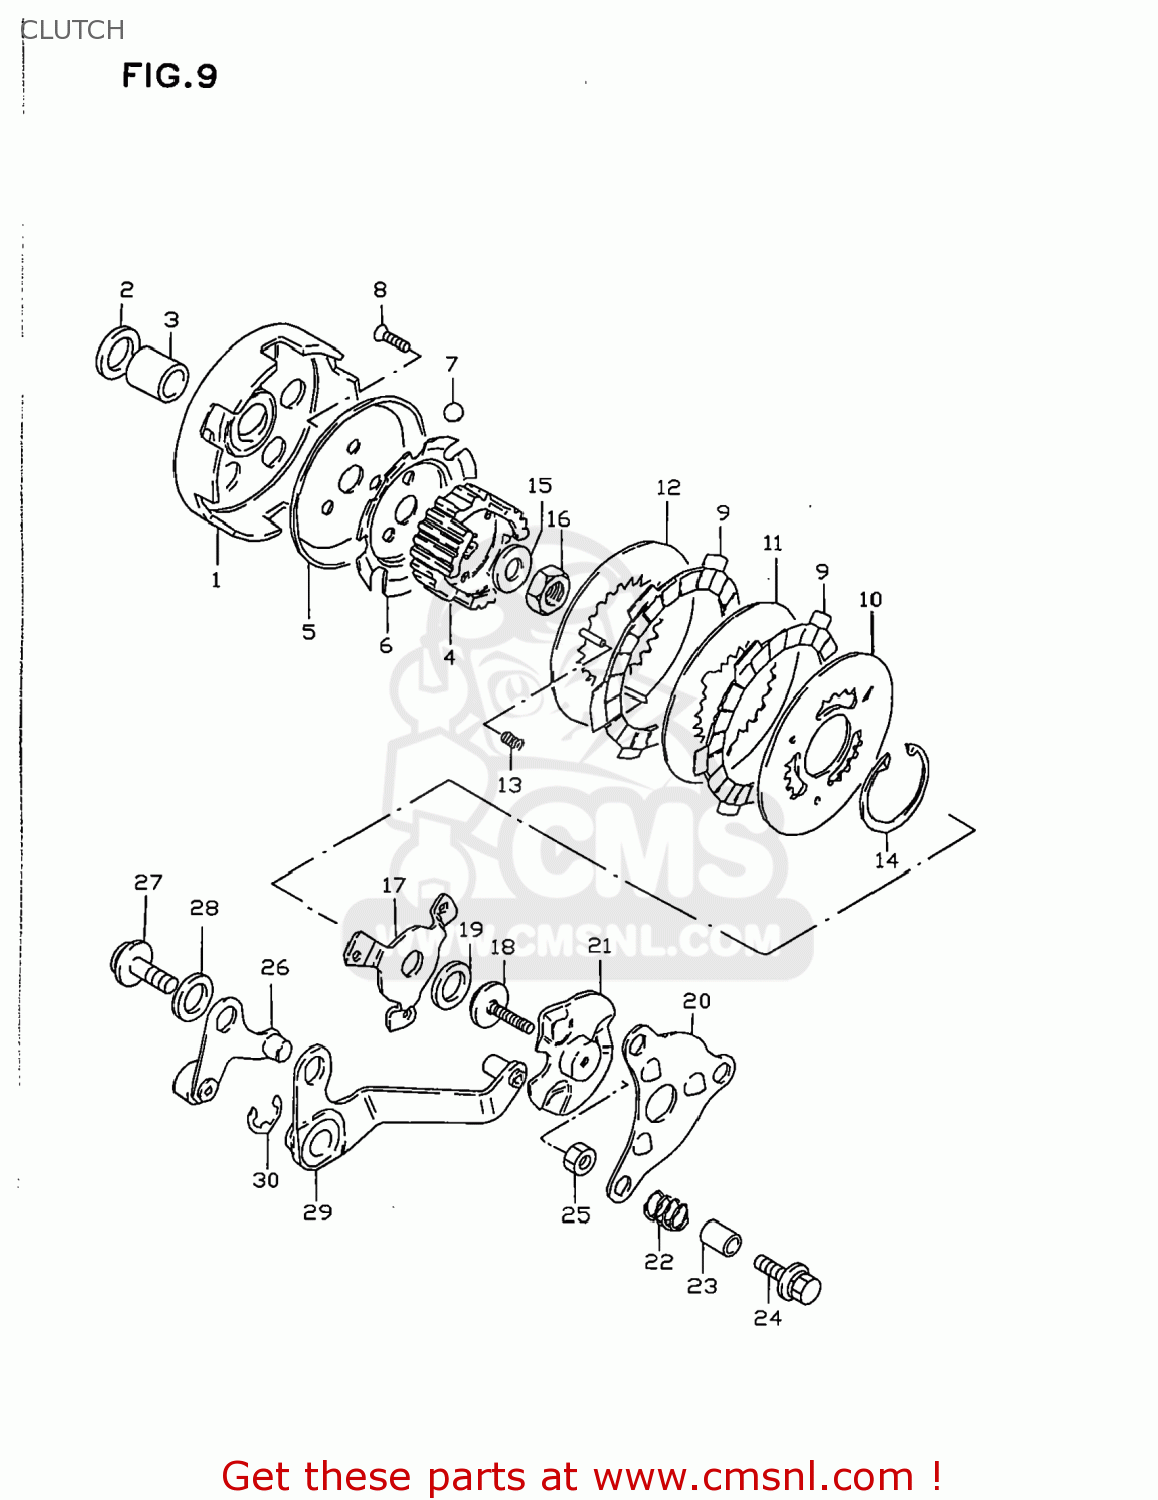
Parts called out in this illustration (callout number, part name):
1	GEAR,PRIMARY DRIVE
2	WASHER(14X23X3)
3	SPACER(14X19X18)
4	HUB,CLUTCH SLEEVE
5	PLATE,CLUTCH BALL
6	GUIDE,CLUTCH BALL
7	BALL
8	SCREW ,6X16
9	PLATE,CLUTCH DRIVE (NAS)
10	PLATE,CLUTCH DRIVEN OUTER (NAS)
11	PLATE,CLUTCH DRIVEN (NAS)
12	PLATE,CLUTCH INNER
13	SPRING
14	CIRCLIP
15	WASHER
16	NUT
17	PLATE,CLUTCH PRESSURE
18	PIECE,CLUTCH PUSH
19	BEARING(10X22X2.8)
20	PLATE,CLUTCH RELEASE
21	PLATE,CLUTCH RELEASE,INNER
22	SPRING
23	SPACER(6X9X10.3)
24	BOLT
25	NUT 6MM
26	PLATE,CLUTCH RELEASE ARM LINK
27	BOLT(8X17)
28	WASHER
29	ARM,CLUTCH RELEASE PLATE
30	E RING
